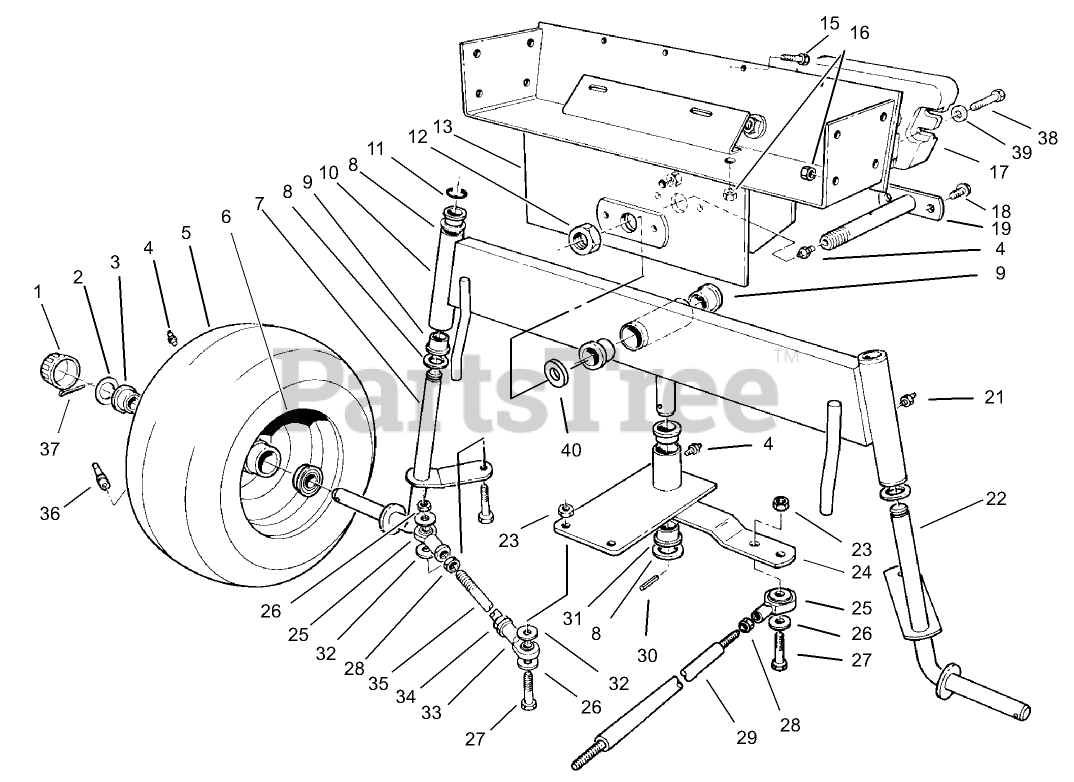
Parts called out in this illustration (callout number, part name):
1	CAP-HUB
2	WASHER-PLAIN
3	Bearing
4	FITTING-GREASE
6	FRONT WHEEL
7	Spindle R.H.
8	WASHER-THRUST
9	BUSHING PM
10	Axle-Rear (Incl. Ref. #9)
11	E-RING
12	NUT-LOCK NI
13	Frame-Rear
15	SCREW-HH
16	NUT-LOCK, NI
17	WEIGHT-REAR
18	SCREW-HHFTF
19	Axle-Pivot
21	GREASE FITTING
22	Spindle LH.
23	NUT-LOCK, NI
24	Plate-Pivot (Incl. Ref. 31)
25	BALL JOINT RH
26	WASHER-FLAT
27	SCREW-HH
28	NUT-JAM
29	Rod-Steering
30	PIN-ROLL
31	BEARING-FLANGE
32	WASHER
33	BALL JOINT LH
35	TIE ROD - STEERING
36	STEM-VALVE
37	PIN-COTTER
38	SCREW-HH
39	WASHER-LOCK
40	WASHER-FLAT
